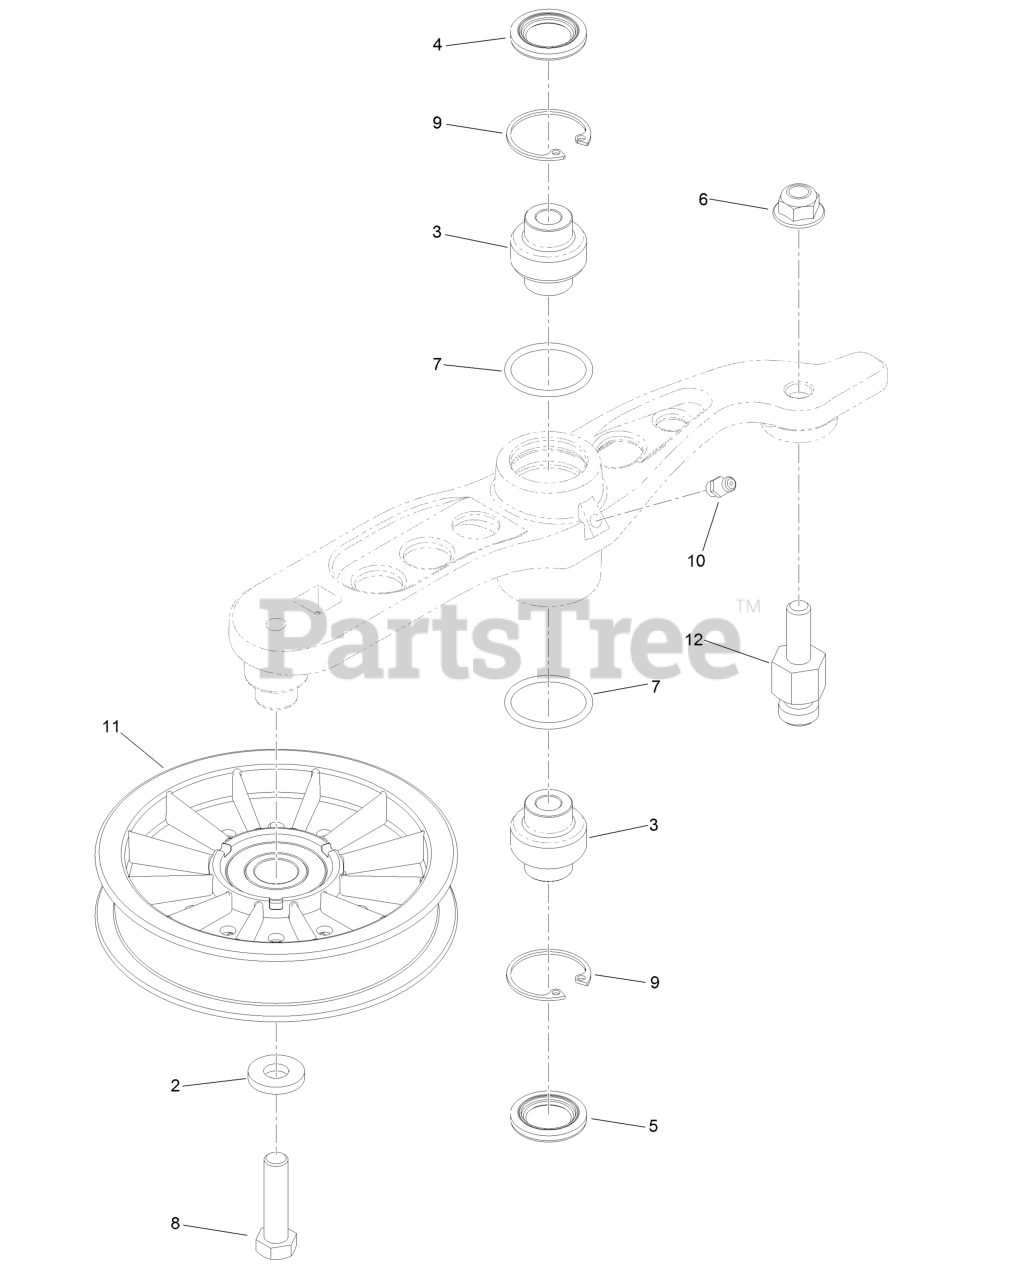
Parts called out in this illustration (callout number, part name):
3	Bearing-Spherical
4	Seal-Lip, Double
5	Seal-Lip, Single
6	Nut-Flange, NI
8	Screw-HH
9	Ring-Snap
10	Fitting-Grease
11	Pulley-Idler
12	Pin-Anchor, Spring
